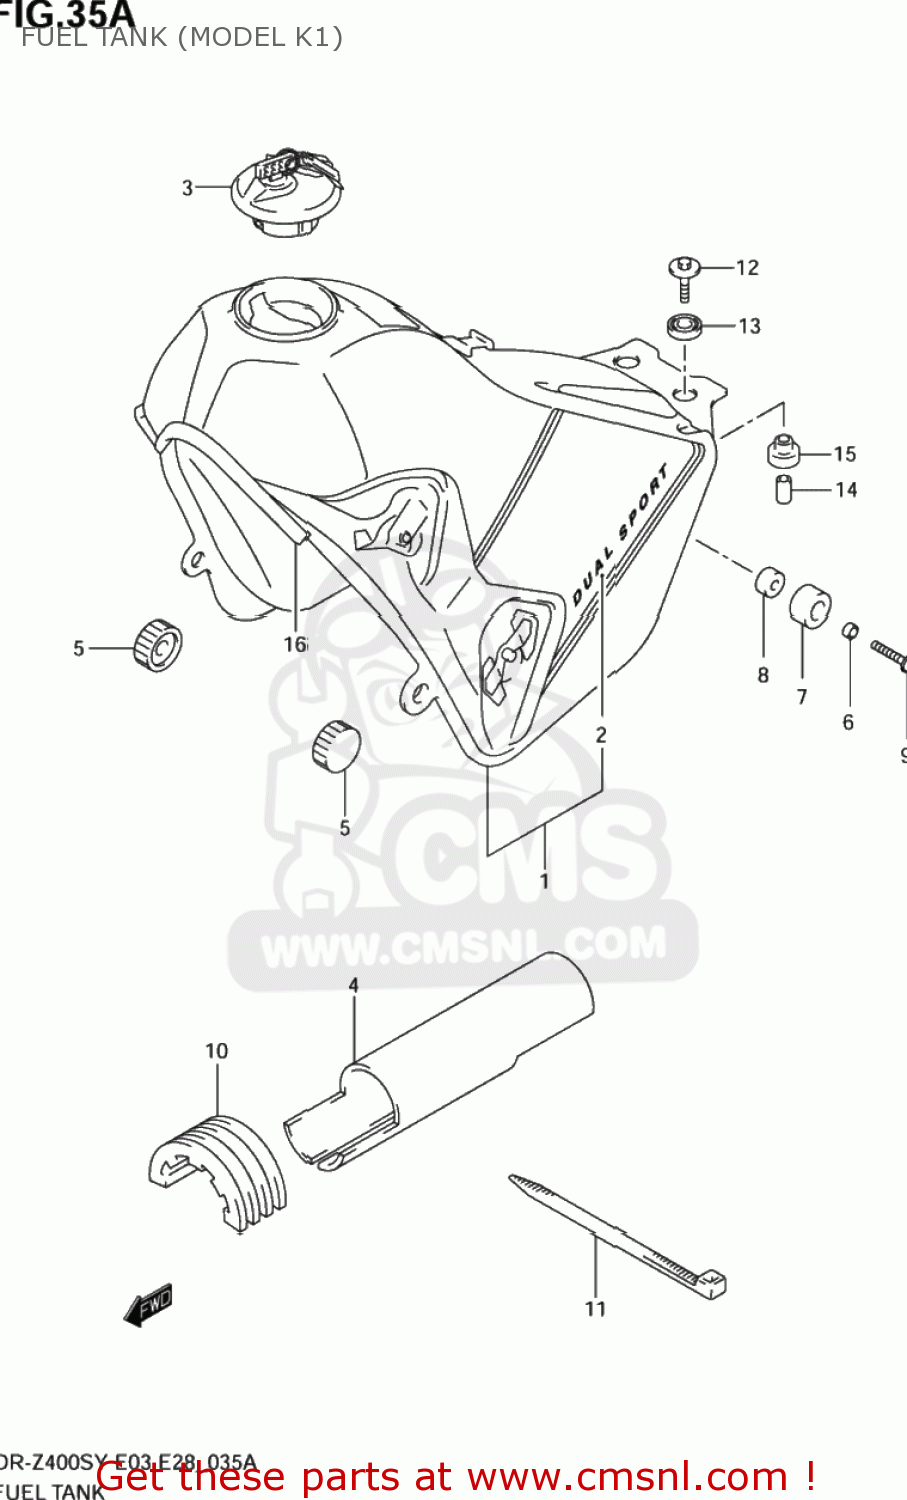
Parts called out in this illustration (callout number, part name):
1	TANK ASSY,FUEL(BLUE)
2	TAPE SET,FUEL TANK
3	CAP SET,FUEL TANK
4	SHIELD,FUEL TANK
5	CUSHION
6	SPACER(6.5X20X9)
7	CUSHION
8	SPACER(6.5X9X5)
9	SCREW
10	CUSHION,FUEL TANK
11	CLAMP(L:300)
12	BOLT(6X30)
13	CUSHION
14	SPACER(6.5X9X18)
15	CUSHION
16	MOLDING
